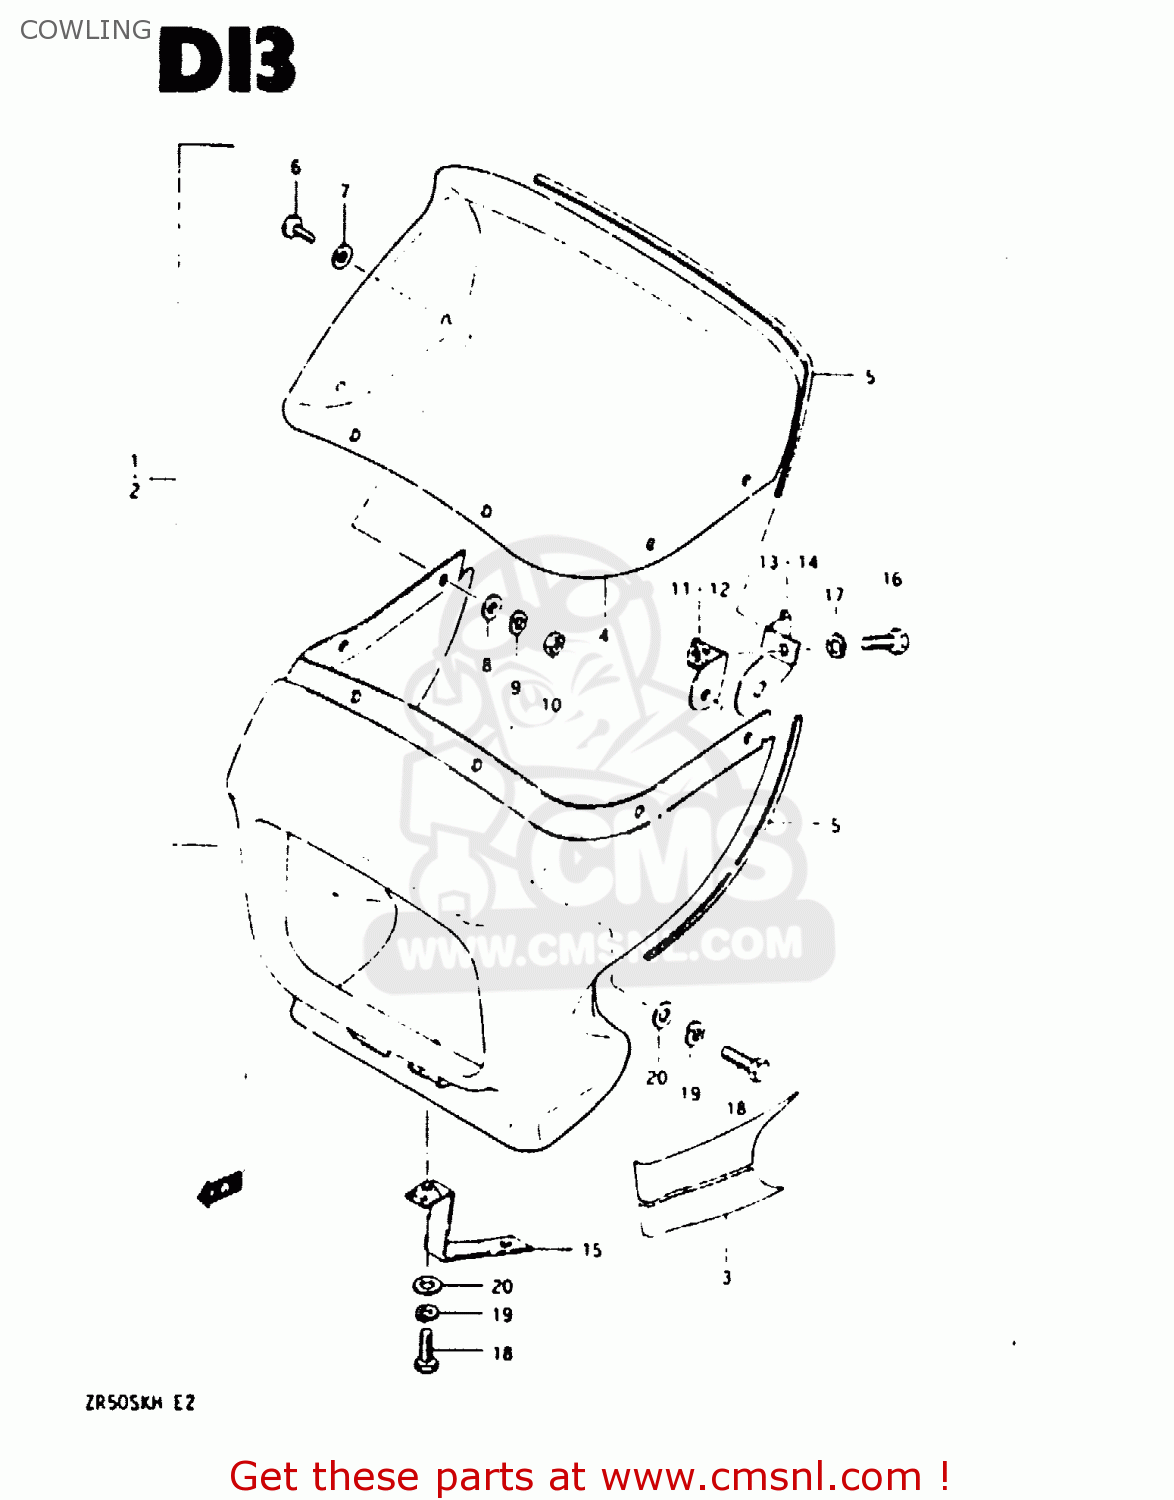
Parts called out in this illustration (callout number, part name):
1	COWLING ASSY (RED)
2	COWLING ASSY (BLACK)
3	TAPE SET
4	WINDOW,COWLING
5	MOLD,COWLING
6	SCREW
7	CUSHION
8	WASHER,5MM
9	WASHER,LOCK
10	NUT ,5MM
11	BRACE, RH (L:19)
12	BRACE,COWLING LH
13	BRACKET, FITTING RH
14	BRACKET, FITTING LH
15	BRACKET, LOWER
16	BOLT
17	WASHER,LOCK
18	BOLT 6X16
19	WASHER,LOCK
20	WASHER (6.5X18X1.6)
